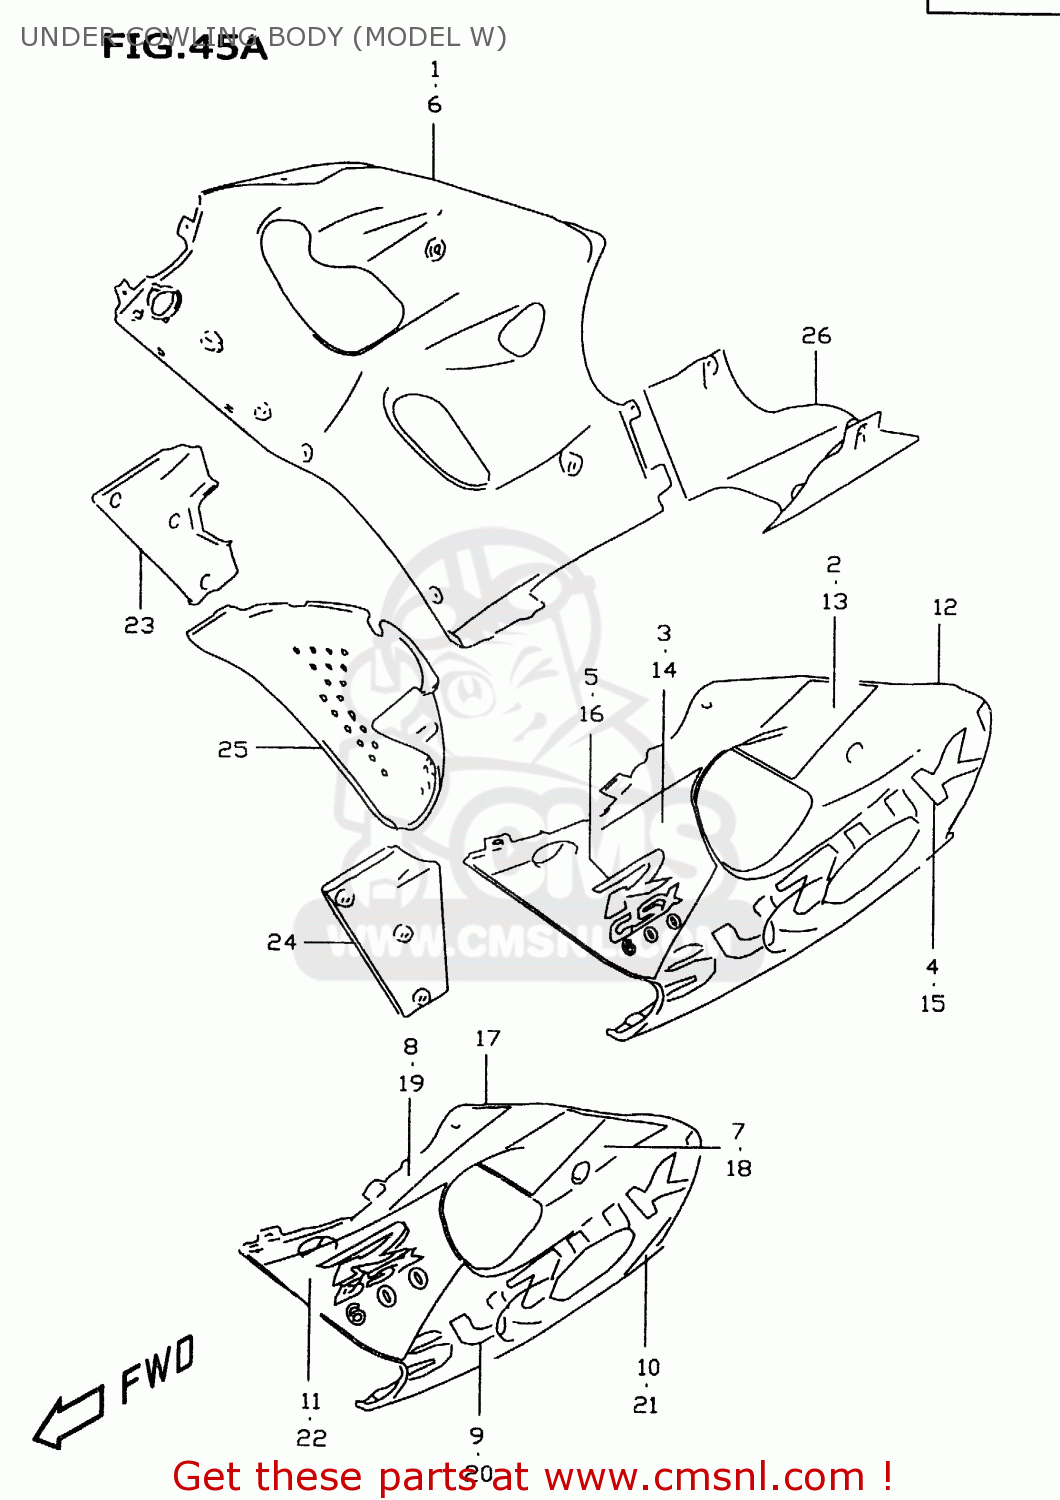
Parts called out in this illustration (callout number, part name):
1	COWLING,UNDER
2	TAPE SET,COWL UNDER,R
3	TAPE,COWL UNDER UPR,R
4	EMBLEM,COWLING UNDER,R
5	EMBLEM,COWLING UNDER,GSXR
6	COWLING ASSEMBLY,UNDER,RIGHT
7	TAPE SET,COWL UNDER,R
8	TAPE SET,COWL UNDER UPR,R
9	EMBLEM,COWLING UNDER,R
10	TAPE,COWL UNDER,R
11	TAPE,COWL UNDER,R
12	COWLING,UNDER
13	TAPE,COWL UNDER,L
14	TAPE,COWL UNDER UPR,L
15	EMBLEM,COWLING UNDER,L
16	EMBLEM,COWLING UNDER,GSXR
17	COWLING ASSEMBLY,UNDER,LEFT
18	TAPE,COWL UNDER,L
19	TAPE SET,COWL UNDER,R
20	EMBLEM,COWLING UNDER,L (WHITE)
21	TAPE,COWL UNDER,R
22	TAPE,COWL UNDER,L
23	COWLING,UNDER INNER,R
24	COWLING,UNDER INNER,L
25	COWLING,UNDER CTR
26	COWLING,UNDER,REAR (SILVER)
